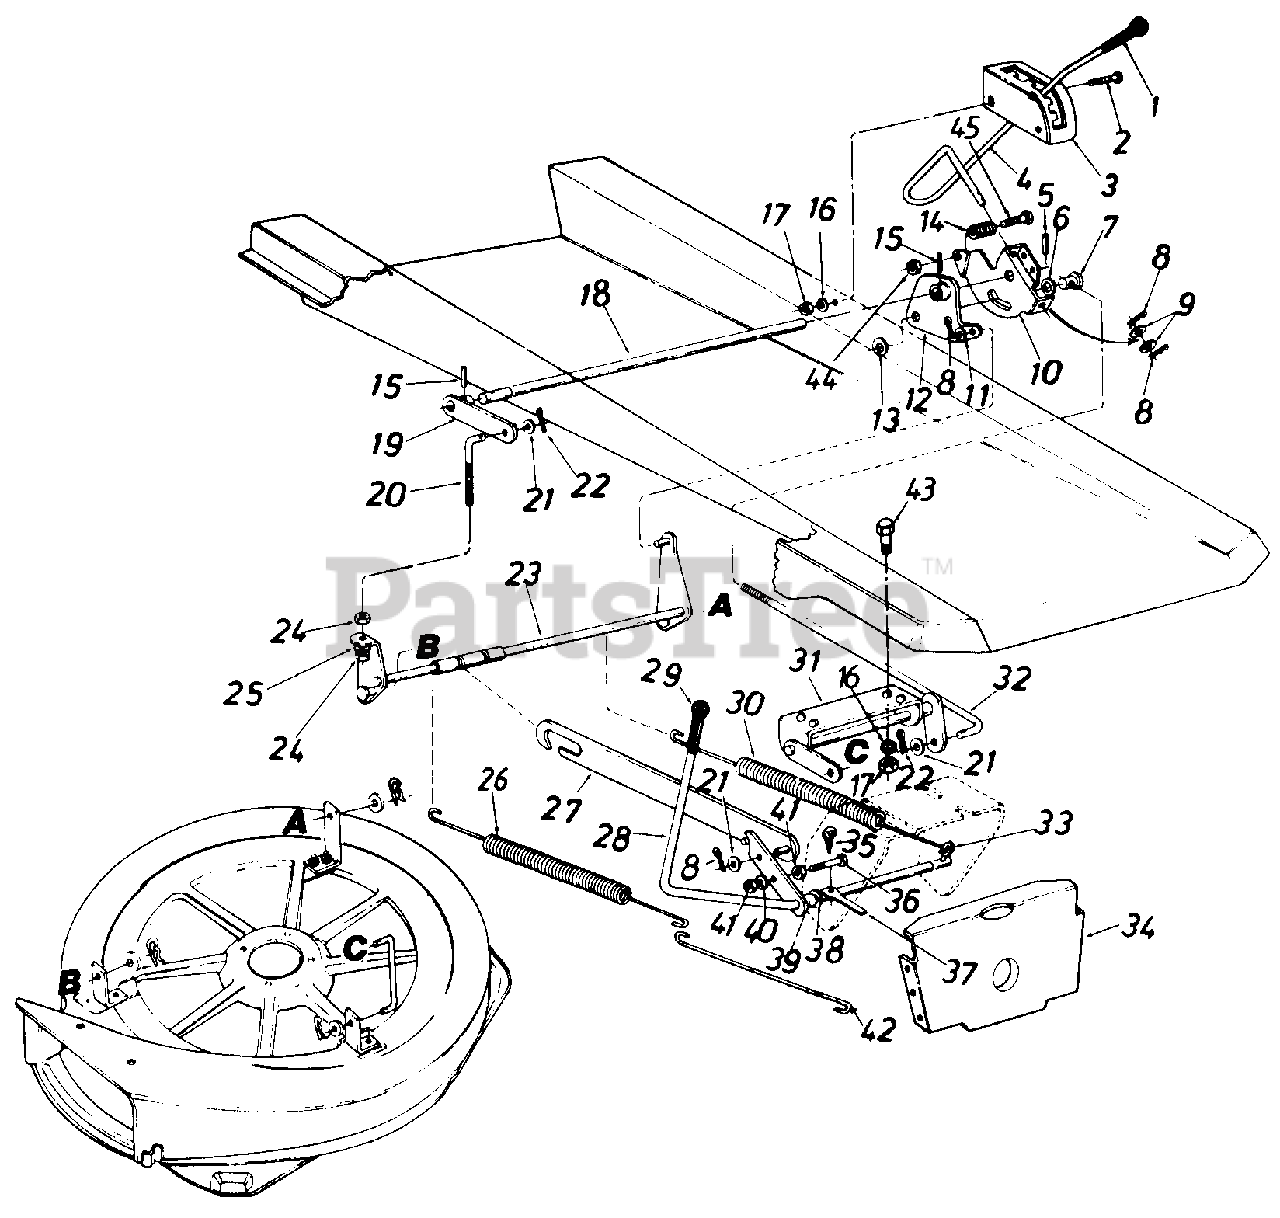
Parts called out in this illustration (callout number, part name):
2	Truss Mach. Scr. 5/16-18 x .75" Lg
5	Spring Pin Spir. 3/16" Dia. x 1.50" Lg.
6	Fl-Wash. .385" I.D. x .87" O.D.
7	Adj. Ferrule Deck Lift Handle
8	Cotter Pin 1/8" Dia. x 1.0"
9	Fl-Wash. .531" I.D. x .930" O.D.
12	Deck Lift Brkt. Ass'y. - L.H.
13	Fl-Wash. .635" I.D. x 1.04" O.D.
14	Compression Spring, 5" Dia. x .9" Lg.
15	Spring Pin Spir. 1/4" Dia. x 1.50" Lg.
16	L-Wash. 5/16" I.D.
17	Hex Nut 5/16-18 Thd.
18	Rear Hgt. Adj. Shaft
19	Deck Lift Brkt. Ass'y. - R.H.
20	Deck Adj. Scr. 3/8-16 Thd.
21	Fl-Wash. .385" I.D. x .87" O.D.
22	Intern. Cotter Pin 1/2" Dia.
23	Deck Link Ass'y. - Rear
24	Hex Nut 3/8-16 Thd.
25	L-Wash. 3/8" I.D.
26	Extension Spring 13.84" Lg.
30	Extension Spring .73" O.D. x 13.84" Lg.
31	Deck Lift Ass'y. - Front
32	Deck Lift Connecting Rod
33	Clevis Pin Special .250" Dia.
36	Hex Bolt 5/16-18 x 1.50" Lg. (Grade 5)
37	Switch Actuator
38	Fl-Wash. .531" I.D. x .930" O.D.
39	Spacer .511" I.D. x .70" O.D. x .38" Lg.
40	L-Wash. 5/16" I.D.
41	Hex Nut 5/16-18 Thd.
43	Hex Bolt 5/16-18 x .75" Lg.
44	Hex Cent. L-Nut 1/4-20 Thd.
45	Hex Bolt 1/4-20 x 1.25" Lg.
